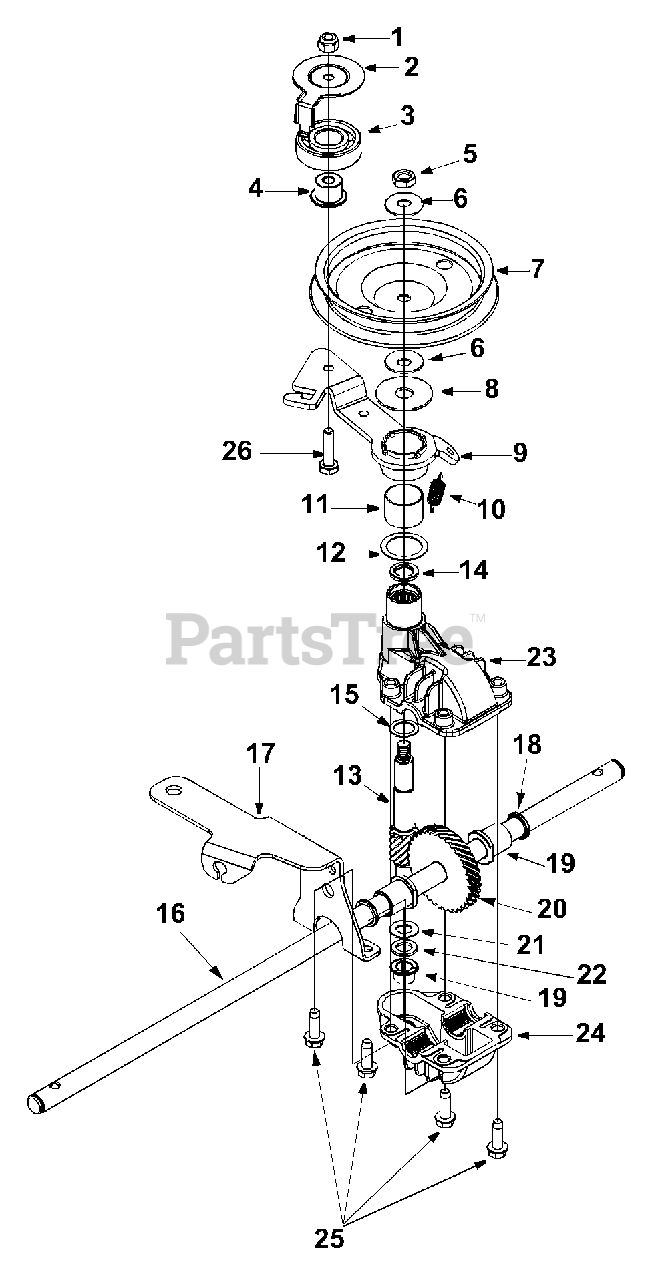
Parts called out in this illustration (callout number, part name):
1	L-Nut 1/4-28
2	Belt Keeper
3	Ball Bearing
4	Flange Bearing
5	Hex Jam Nut 5/16-24
6	Bell Washer.325 x.930 x.45
7	Pulley, 3.82 x.313 x.68
8	Flat Washer.422 x 1.38 x.060
9	Idler Bracket Pulley
10	Extension Spring
11	Bearing Sleeve
12	Fl-Wash.865 x 1.145 x.030
13	Pinion Shaft 10T
14	Needle Bearing.438 x.625 x.500
15	Fl-Wash.504 x.700 x.030
16	Transmission Assembly Comp.
17	Idler Cable Bracket Assembly
18	Oil Seal.500 x.687 x.094
19	Flange Bearing
20	Output Shaft
21	Thrust Washer.375 x.070 x.030
22	Thrust Washer.388 x.625 x.062
23	Upper Housing
24	Lower Housing
25	Hex Screw w/Washer 1/4-20 x.750
26	Hex Screw, 1/4-28 x 1.00
